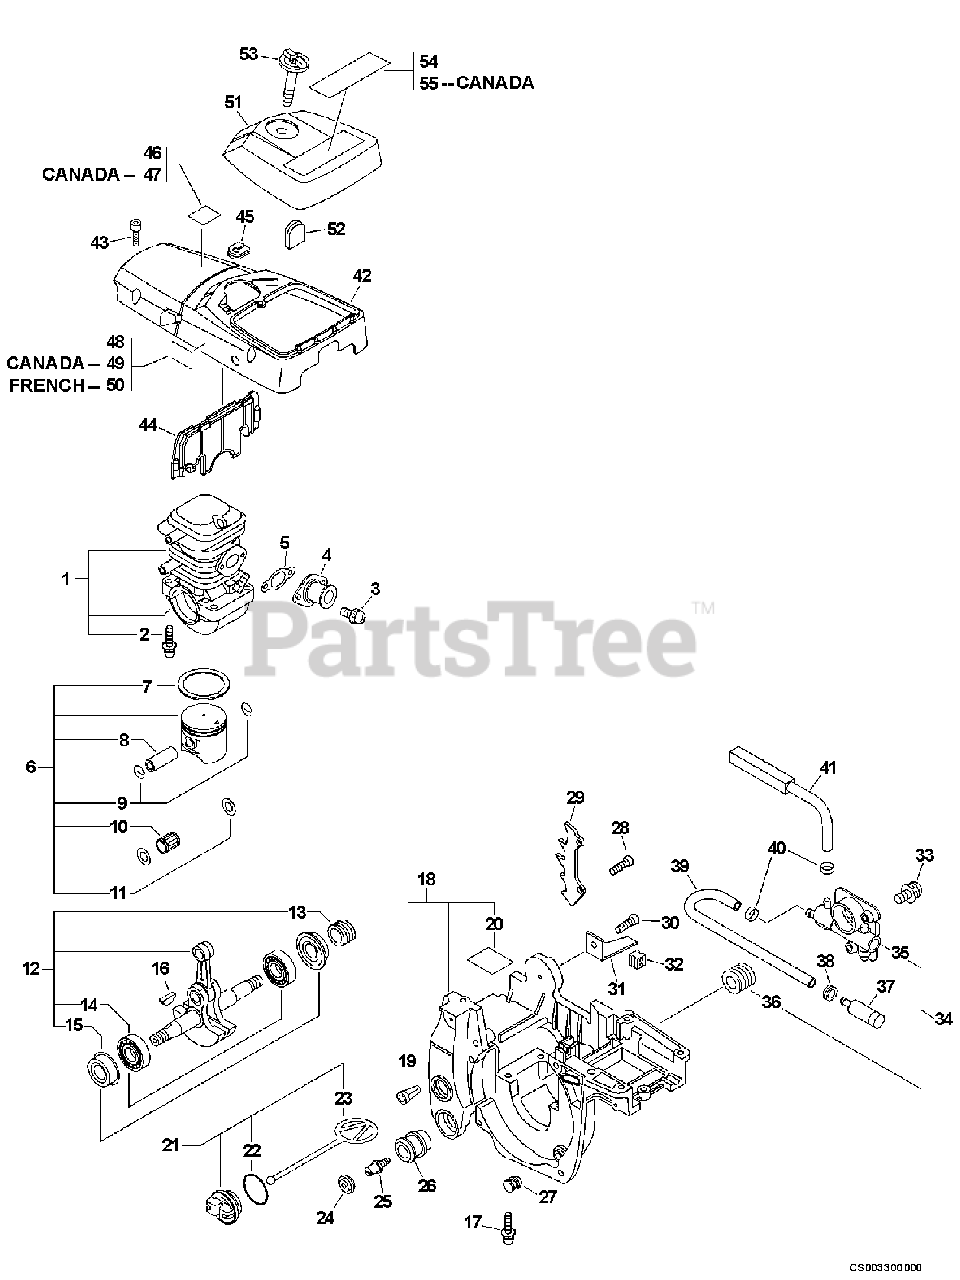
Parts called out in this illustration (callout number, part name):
1	CRANKCASE SET
3	SCREW 5×14
4	BELLOWS, INTAKE
5	GASKET, INTAKE
6	PISTON KIT
7	RING, PISTON
8	PIN, PISTON
9	RING, SNAP
10	BEARING, NEEDLE 9
11	WASHER, THRUST
12	CRANKSHAFT ASSY
13	GEAR, WORM
14	BEARING, BALL - 6201 C3
15	SEAL, OIL 12
16	KEY, WOODRUFF
17	BOLT 5×30
18	ENGINE COVER ASSY
19	VENT ASSY
20	SHIELD, HEAT
21	CAP ASSY
22	O-RING 25
23	CONNECTOR, CAP L= 60 MM
24	CAP, CUSHION
26	CUSHION 5
27	CUSHION
28	SCREW TAPPING 5×20
29	SPIKE, BUMPER
30	SCREW TAPPING 5×16
31	CHAIN CATCHER
32	GROMMET, LEAD
33	SCREW 4×12
34	AUTO-OILER KIT
35	BELLOWS, INTAKE
35	AUTO-OILER ASSY
36	SCREW 5×14
36	GEAR, WORM
37	GASKET, INTAKE
37	FILTER, OIL
39	PIPE, OIL
40	CLIP Ø6.5 MM
41	PIPE, OIL OUTLET
42	COVER, ENGINE
43	SCREW 5×20
44	PLATE, INSULATOR
45	GROMMET
47	LABEL, BAR & CHAIN
48	LABEL, UL - KICK BACK
49	LABEL, KICK BACK
50	LABEL, KICK BACK - FRENCH
51	COVER ASSY, AIR FILTER
53	THUMBSCREW
54	LABEL - MODEL CS-370
55	LABEL - MODEL CS-370
